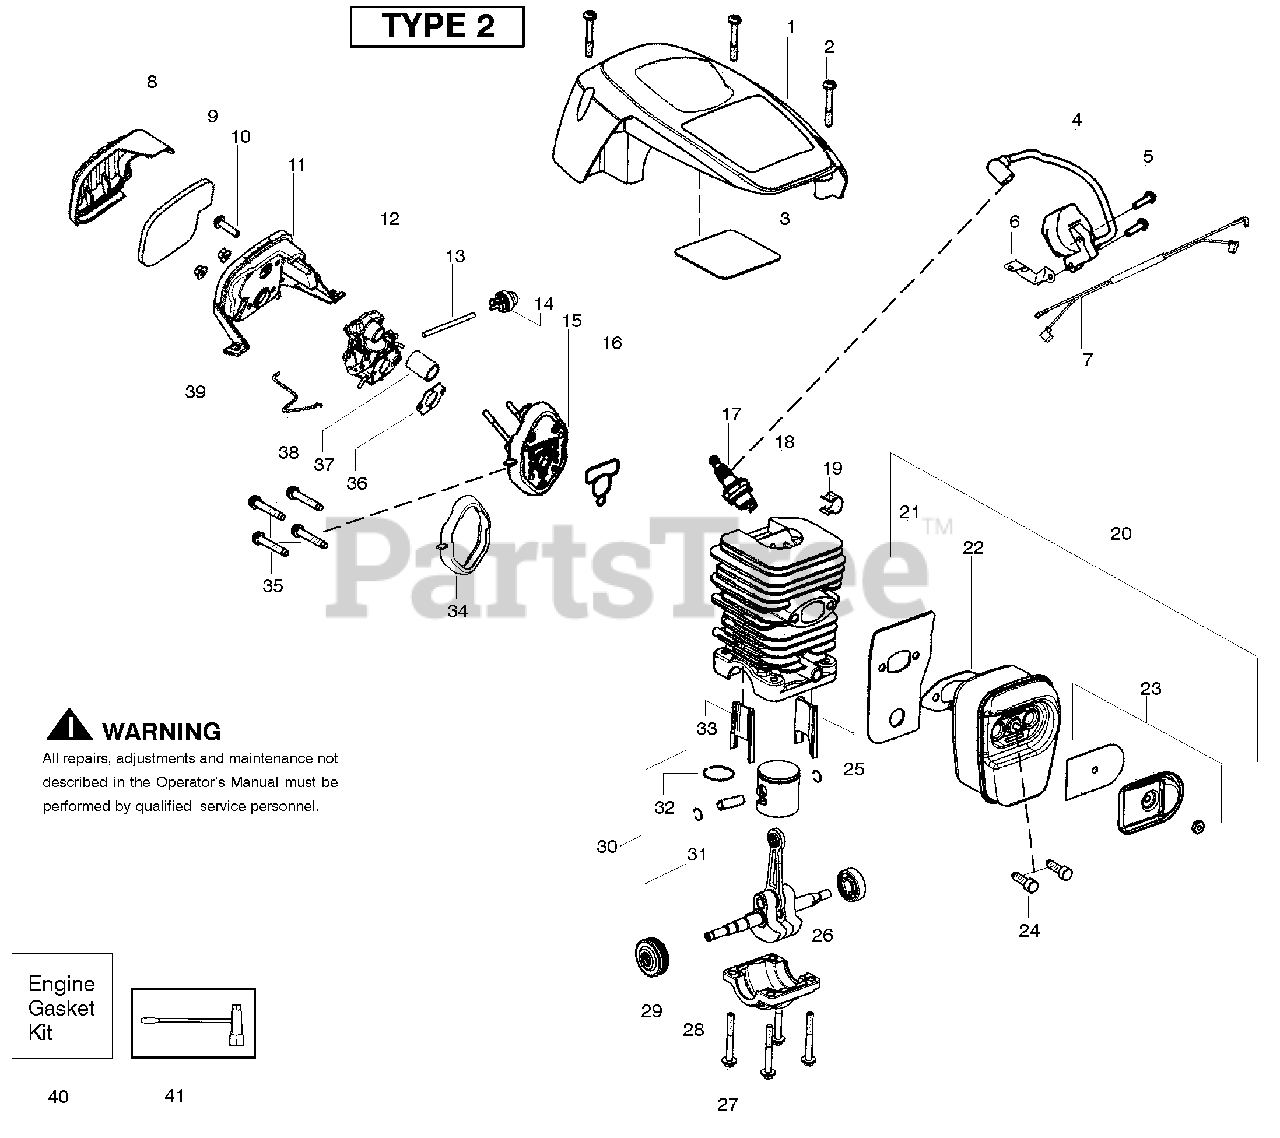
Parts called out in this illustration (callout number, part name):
1	Shield-Cylinder
3	Reflector-Tape
4	Module - Ignition
6	Strap-Ground
7	Assy-Wire Harness
8	Cover-Air Filter
9	Filter-Air
11	Housing-Air Filter
12	Carburetor Zama W-26
13	Kit-Fuel Line (Small)
14	Bulb-Purge "snap-in"
15	Kit-Carb. Adaptor
16	Gasket-cyl. o-ring (kit)
17	Accy-Spark Plug (RCJ-7Y)
18	Kit-Cylinder
19	Clip-High Tension Lead
20	Kit-Muffler
21	Backplate-Muffler
22	Gasket-Muffler (kit)
23	Kit-Spark Arrestor
24	Bolt-Muffler
25	Insert-Left (black) Cyl.
26	Assy-Crankshaft/Rod
28	Cap-Crankcase
29	Assy-Bearing/Seal
30	Kit-Piston
31	Retainer-Piston Pin
32	Ring-Piston
33	Insert-Right (gray) Cyl.
34	Seal-Adaptor (kit)
36	Gasket-Carb. (kit)
37	Tube-Intake
38	Wire-Throttle
39	Nut-Carb.
40	Kit-Gasket
41	Scrench
